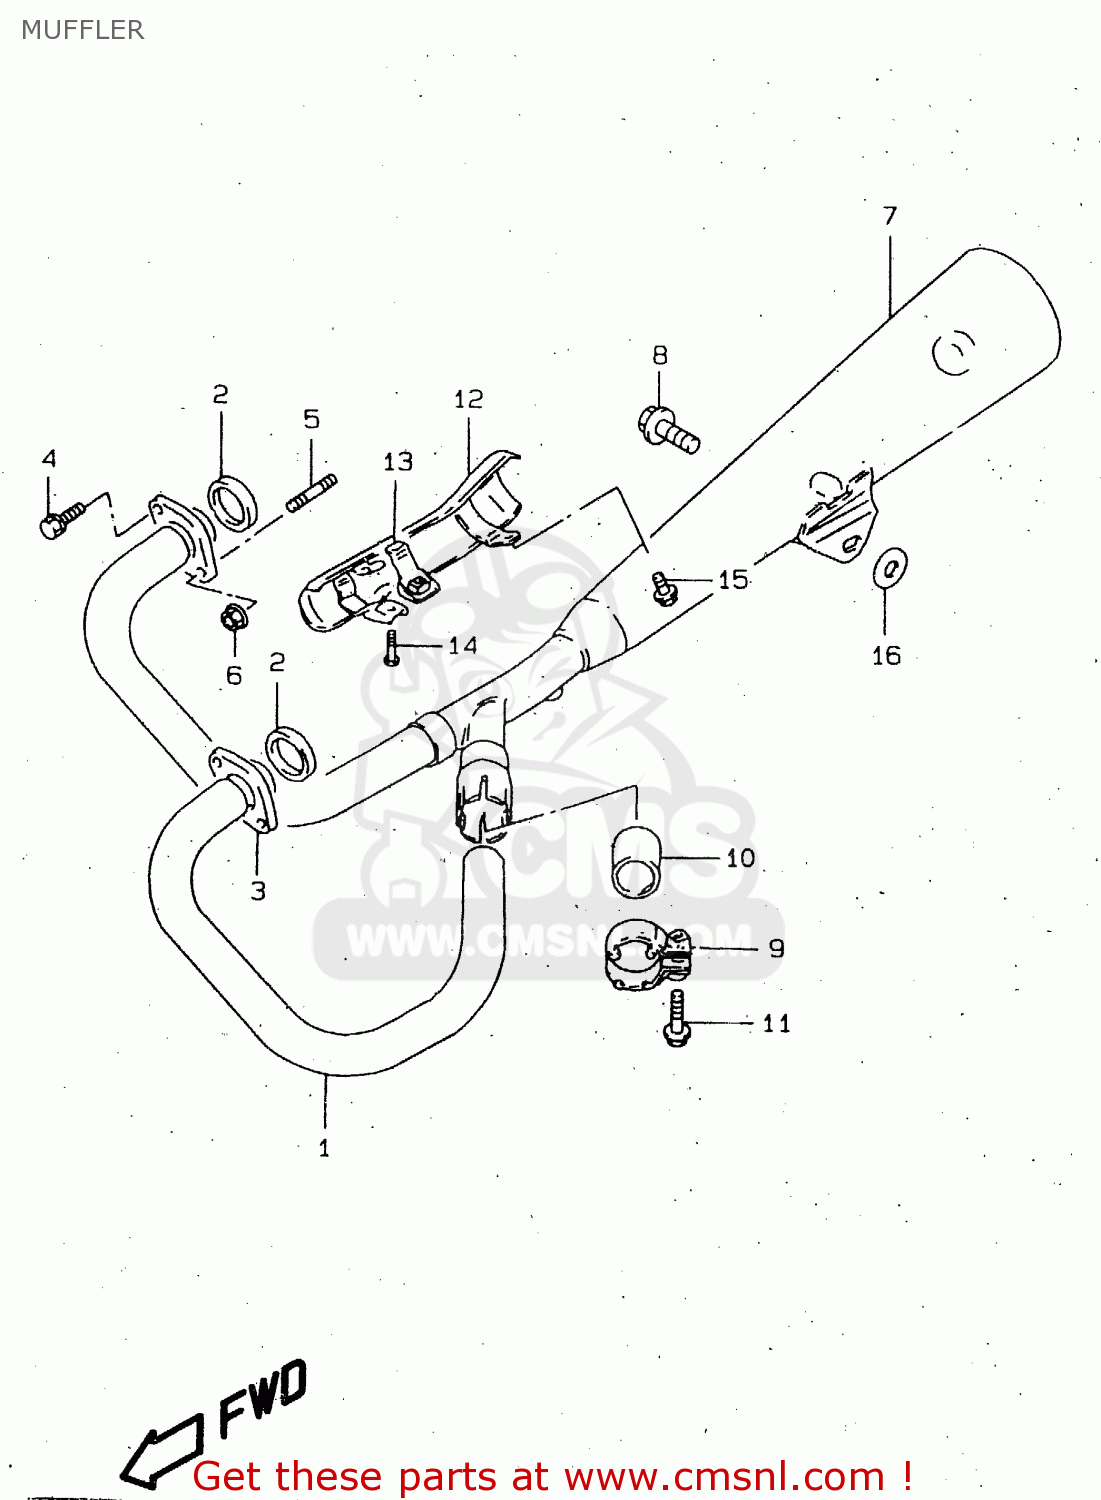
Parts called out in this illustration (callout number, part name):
1	PIPE,EXHAUST,L
2	GASKET,EXHAUST PIPE (NAS)
3	CLAMP
4	BOLT
5	STUD 6X20
6	NUT
7	MUFFLER COMP
8	BOLT
9	CLAMP
10	CONNECTOR,MUFFLER
11	BOLT
12	COVER,MUFFLER
13	CLAMP,MUFFLER COVER
14	SCREW
15	SCREW
16	WASHER
